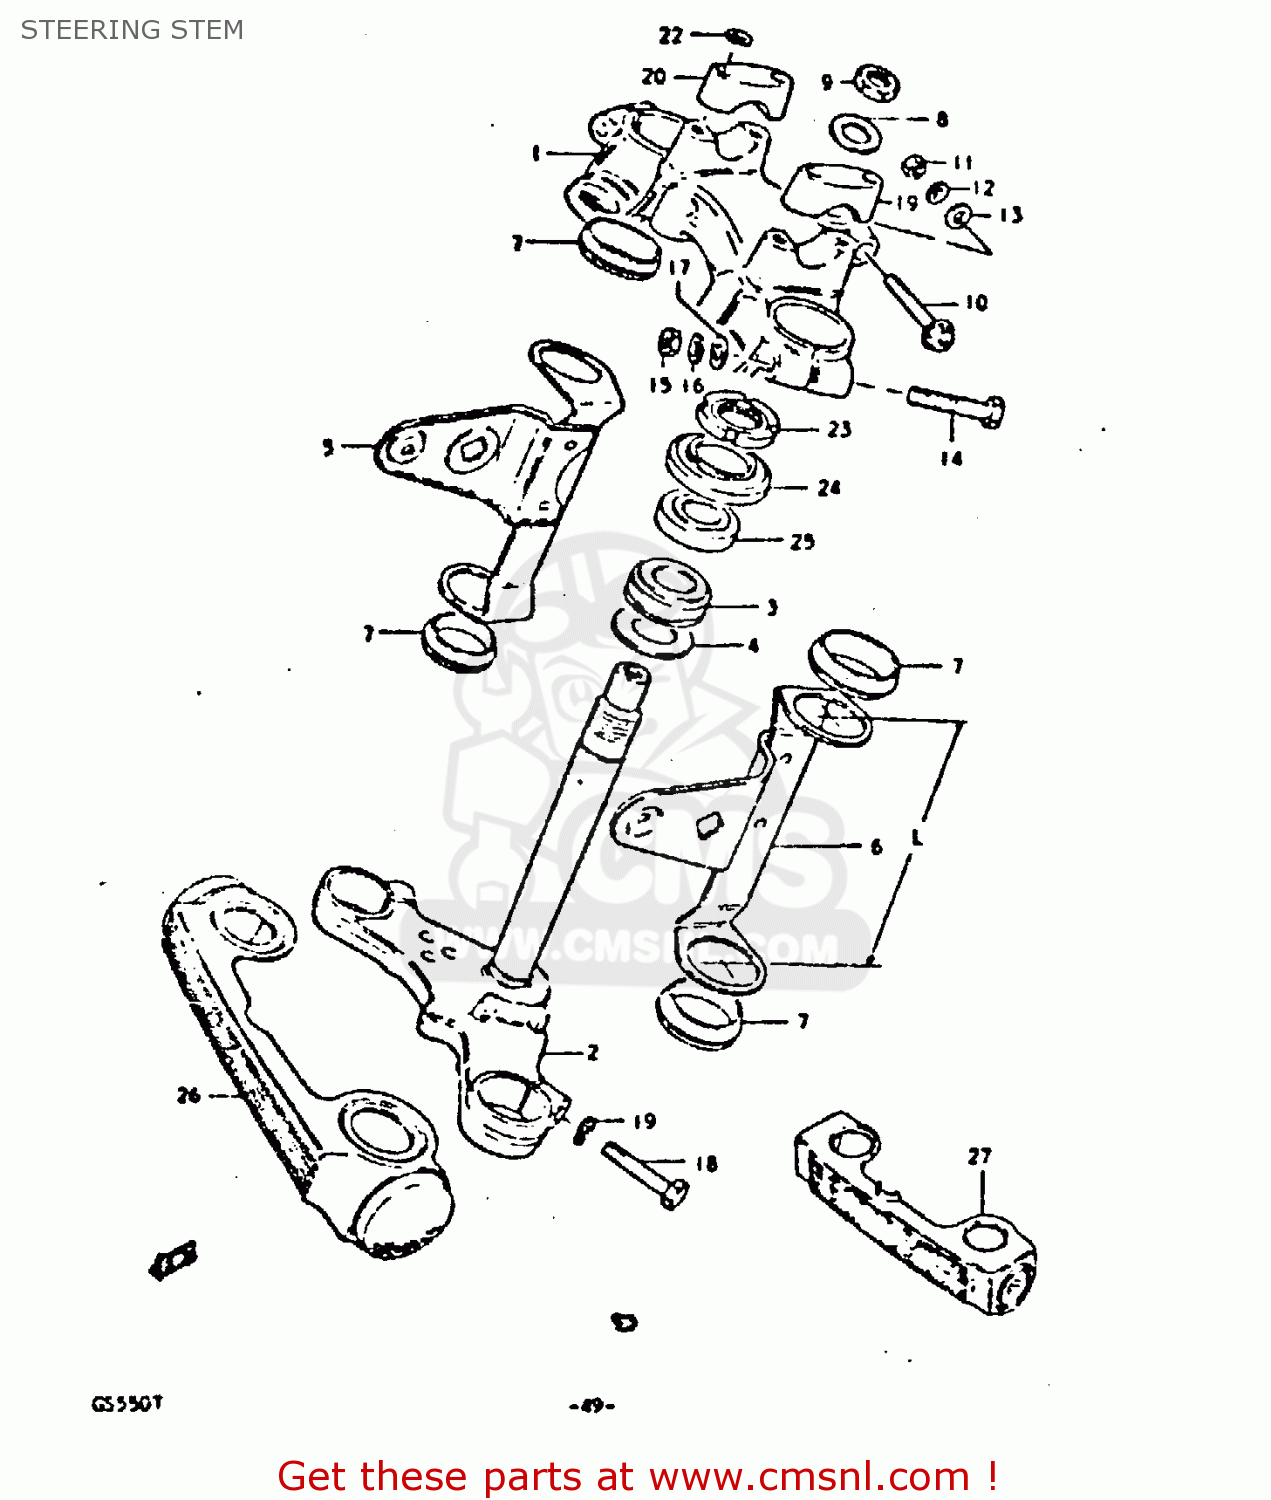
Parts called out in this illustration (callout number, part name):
1	HEAD,STEERING STEM
2	STEM,STEERING
3	BEARING
4	WASHER,THRUST
5	BRACKET,HEADLAMP,RIGHT
6	BRACKET,HEADLAMP,LEFT
7	CUSHION,HEADLAMP BRACKET
8	WASHER
9	NUT,FR FORK UPR BRACKET
10	BOLT
11	NUT
12	LOCK WASHER
13	WASHER
14	BOLT 10X55
15	NUT
16	LOCK WASHER
17	WASHER
18	BOLT 10X40
19	LOCK WASHER
20	HOLDER,HANDLE UPR
21	BOLT
22	LOCK WASHER
23	NUT,STEERING STEM(25X44X10)
24	DUST SEAL,STEERING,UPPER
25	TAPER,ROLLER BEARING
26	COVER,FR FORK
